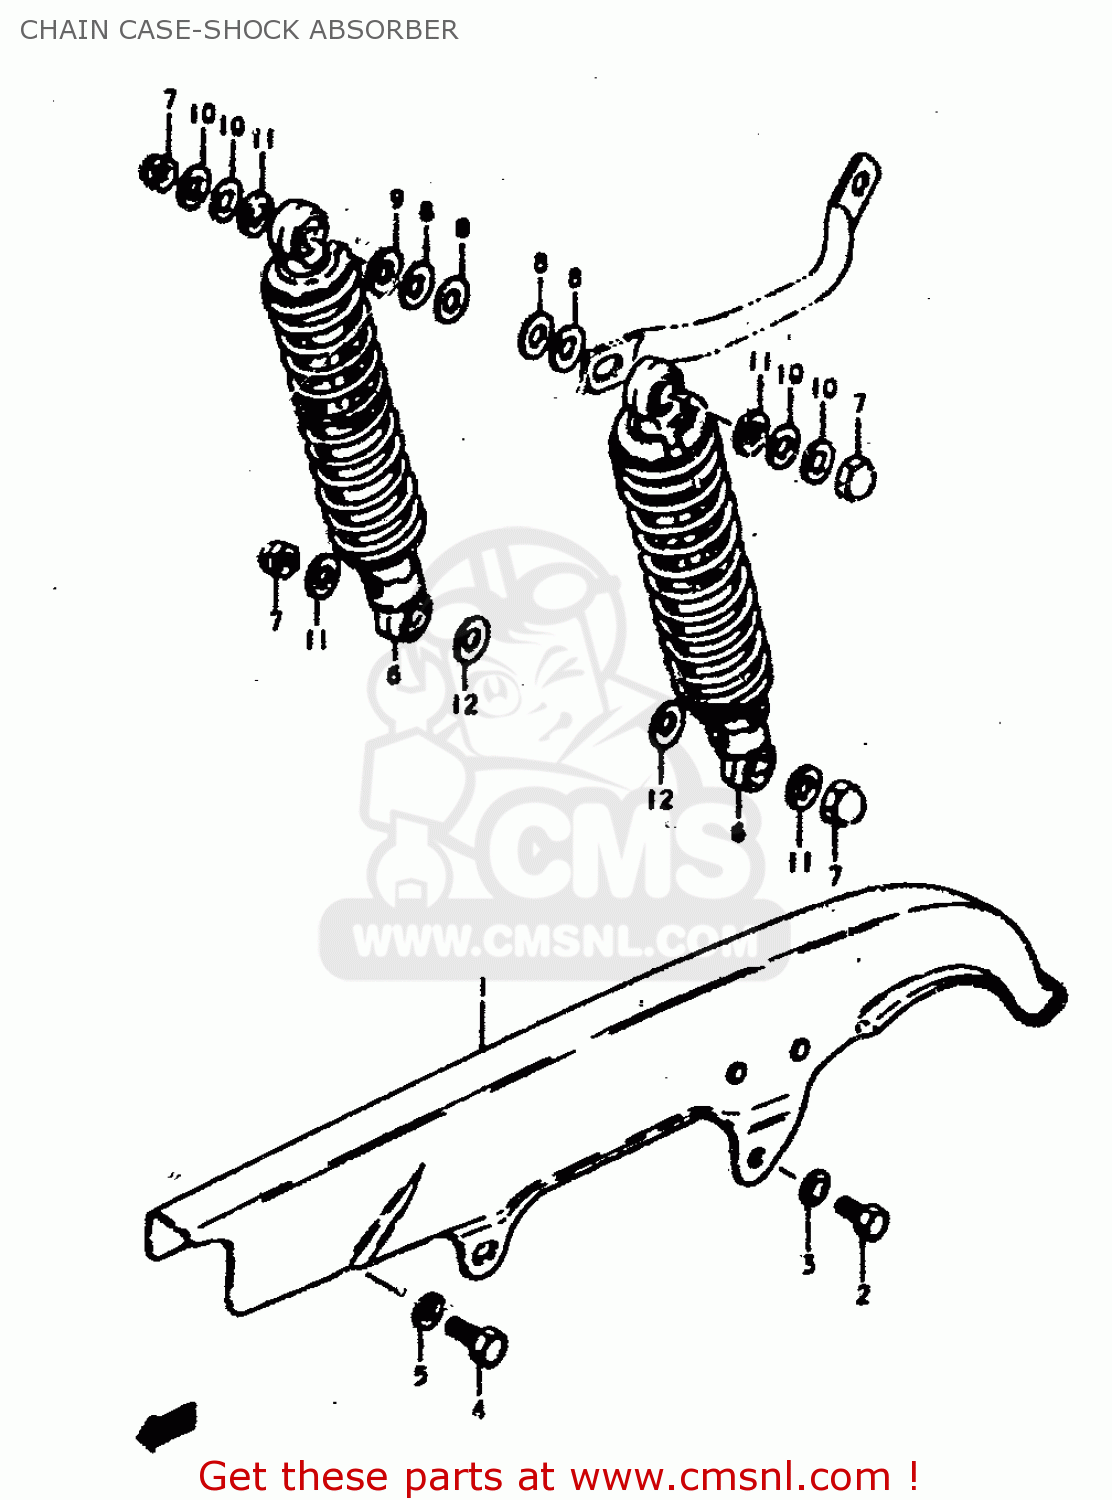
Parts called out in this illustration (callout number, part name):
1	CASE,CHAIN
2	BOLT(6X8)
3	WASHER
4	BOLT
5	WASHER(6.5X18X1)
6	ABSORBER ASSEMBLY,REAR SHOCK
7	NUT, LOWER LH
8	WASHER
9	WASHER (12.5X24X3.2)
10	WASHER
11	WASHER(10.5X24X3.2)
12	WASHER (12.5X24X1.6)
